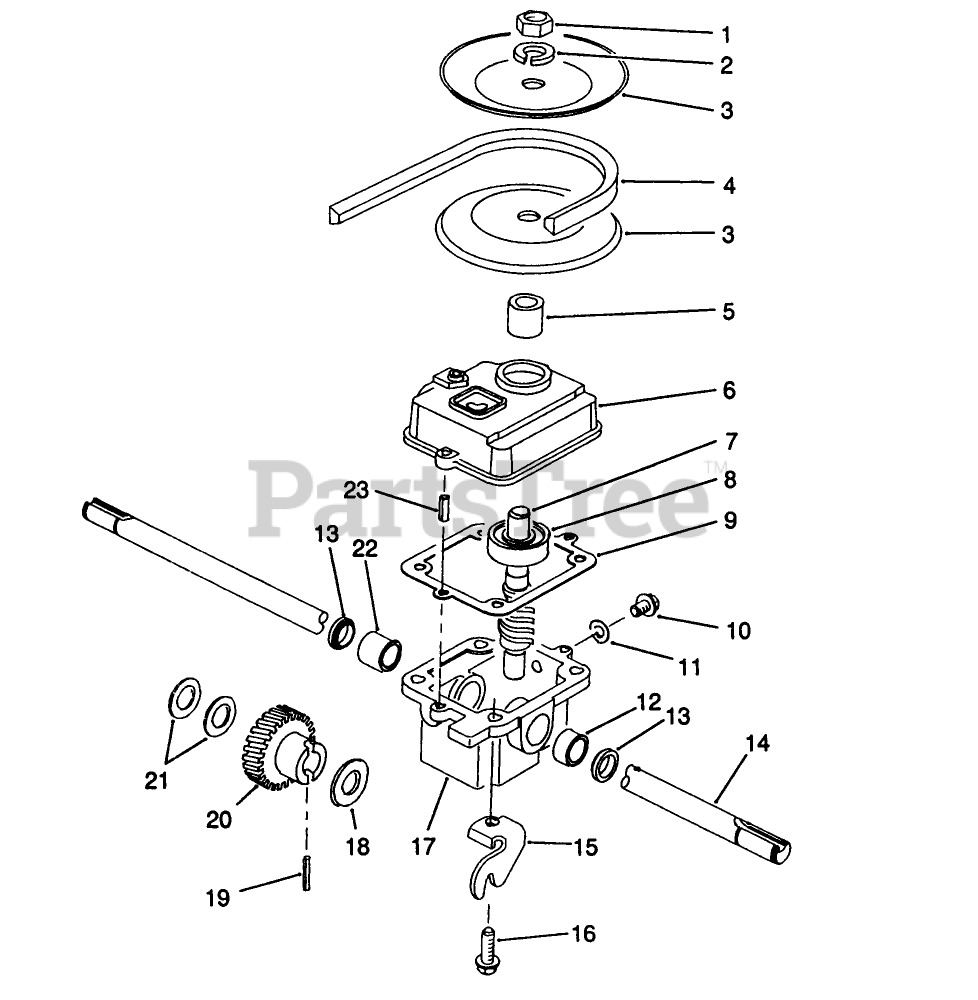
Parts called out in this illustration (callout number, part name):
1	NUT-JAM
2	WASHER-LOCK
3	PULLEY-DRIVEN HALF
8	BEARING - BALL
9	GASKET
10	NYLON SCREW
11	FILL PLUG GASKET
12	BUSHING
13	SEAL-OIL
16	SCREW-HWHTF
18	THRUST WASHER
19	PIN-SPRING
20	GEAR - HELICAL
21	WASHER-PLAIN
22	BUSHING
23	3/16 X 1/2 ROLL PIN
